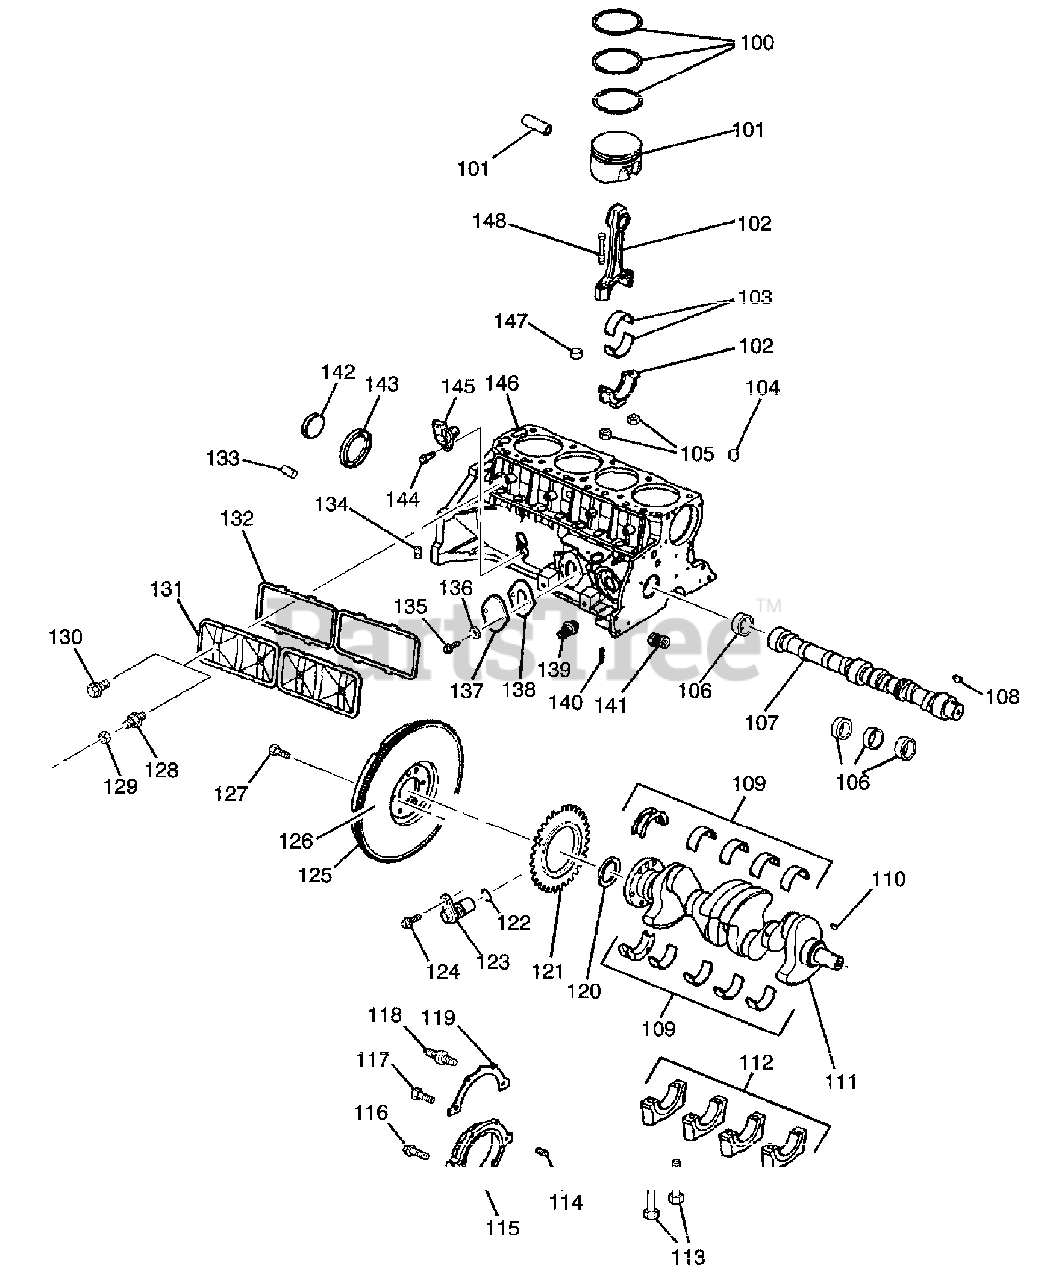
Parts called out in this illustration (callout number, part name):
100	* RING KIT .030 OS
100	* RING KIT
101	* PISTON
102	* ROD
103	* BEARING KIT STD
103	* BEARING KIT .001 OS
104	* BEARING
105	* NUT
106	* BEARING
107	* CAMSHAFT ENG MOBILE
108	* KEY
109	* BEARING KIT #5 .001 OS
109	* BEARING KIT #5 STD
109	* BEARING KIT STD
109	* BEARING KIT .001 OS
110	* KEY
111	* CRANKSHAFT
112	* CAP
113	* BOLT
114	* PIN
115	* HOUSING
116	* BOLT
117	* BOLT
118	* STUD
119	* GASKET
121	* RING
122	* SEAL
124	* BOLT
125	* GEAR
126	* FLYWEEL
127	* BOLT
128	* STUD
129	* NUT
130	* BOLT
131	* COVER
133	* PIN
134	* PLUG
135	* BOLT
136	* WASHER
137	* COVER
138	* GASKET
139	* FITTING
140	* PIN
141	* VALVE
142	*PLUG
143	* PLUG
144	* BOLT
146	* CYLINDER BLOCK
147	* PLUG
148	* BOLT
K01	* CAMSHAFT
